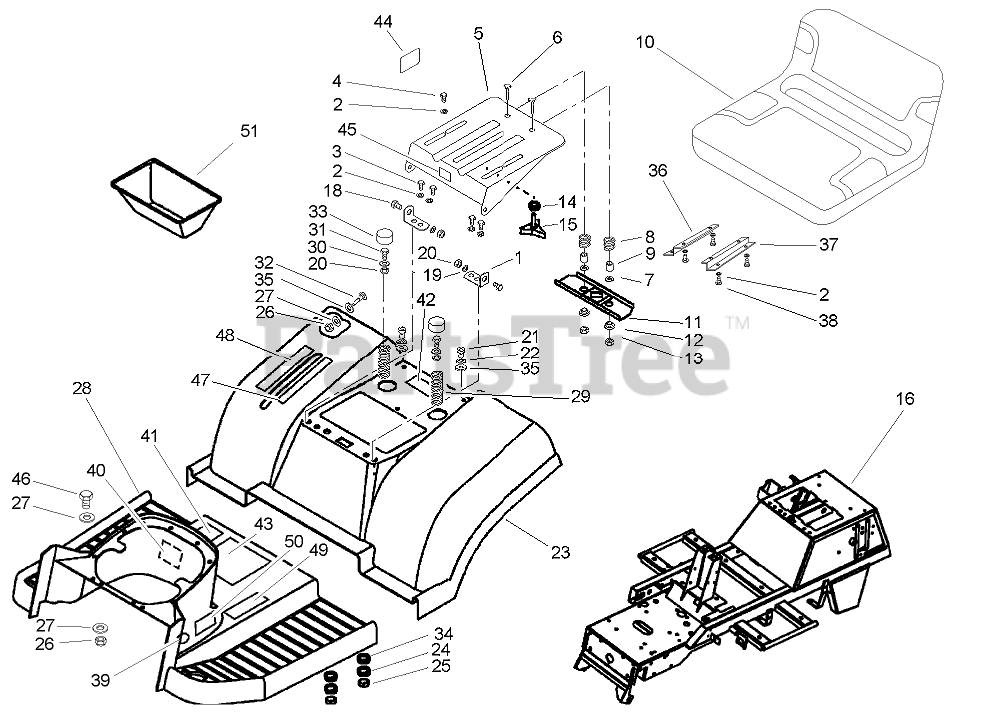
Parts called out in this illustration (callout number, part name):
1	BRACKET-SUPPORT, SEAT
2	WASHER-LOCK, SPRING
3	SCREW-HH
4	SCREW-HH
5	SUPPORT-SEAT
6	BOLT-CARRIAGE
7	WASHER-FLAT
8	SPRING-SEAT
9	SPACER-SPLIT
10	SEAT ASM
11	BRACKET
12	BUSHING
13	NUT-LOCK
14	WASHER-SPRING
15	KNOB-ADJUSTMENT
16	CHASSIS-FRAME
18	SCREW-SUPPORT, SEAT
19	WASHER-PLAIN
20	NUT-LOCK, NI
21	SCREW-HSFH
22	WASHER-FINISH
23	Fender
24	WASHER-FLAT
25	NUT-LOCK, NI
26	NUT-LOCK
27	WASHER-FLAT
28	FOOTREST ASM
29	SPRING-SEAT
30	WASHER-PLAIN
31	SCREW-HH
32	BOLT-CARRIAGE
33	CAP-HUB
34	WASHER-RUBBER
35	WASHER-RUBBER
36	BRACKET-SEAT, RH
37	BRACKET-SEAT, LH
38	Screw
39	DECAL-BRAKE, PARKING
40	DECAL-STARTING
41	DECAL-OPERATION, HYDRO
42	DECAL-BAG TO FRAME
43	DECAL-INSTRUCTION
44	DECAL-SWITCH
45	DECAL-DANGER
46	SCREW-HH
47	DECAL-HOC, LH
48	DECAL-HOC, RH
49	DECAL-OPERATION
50	DECAL-TOWER
51	Box-Battery
